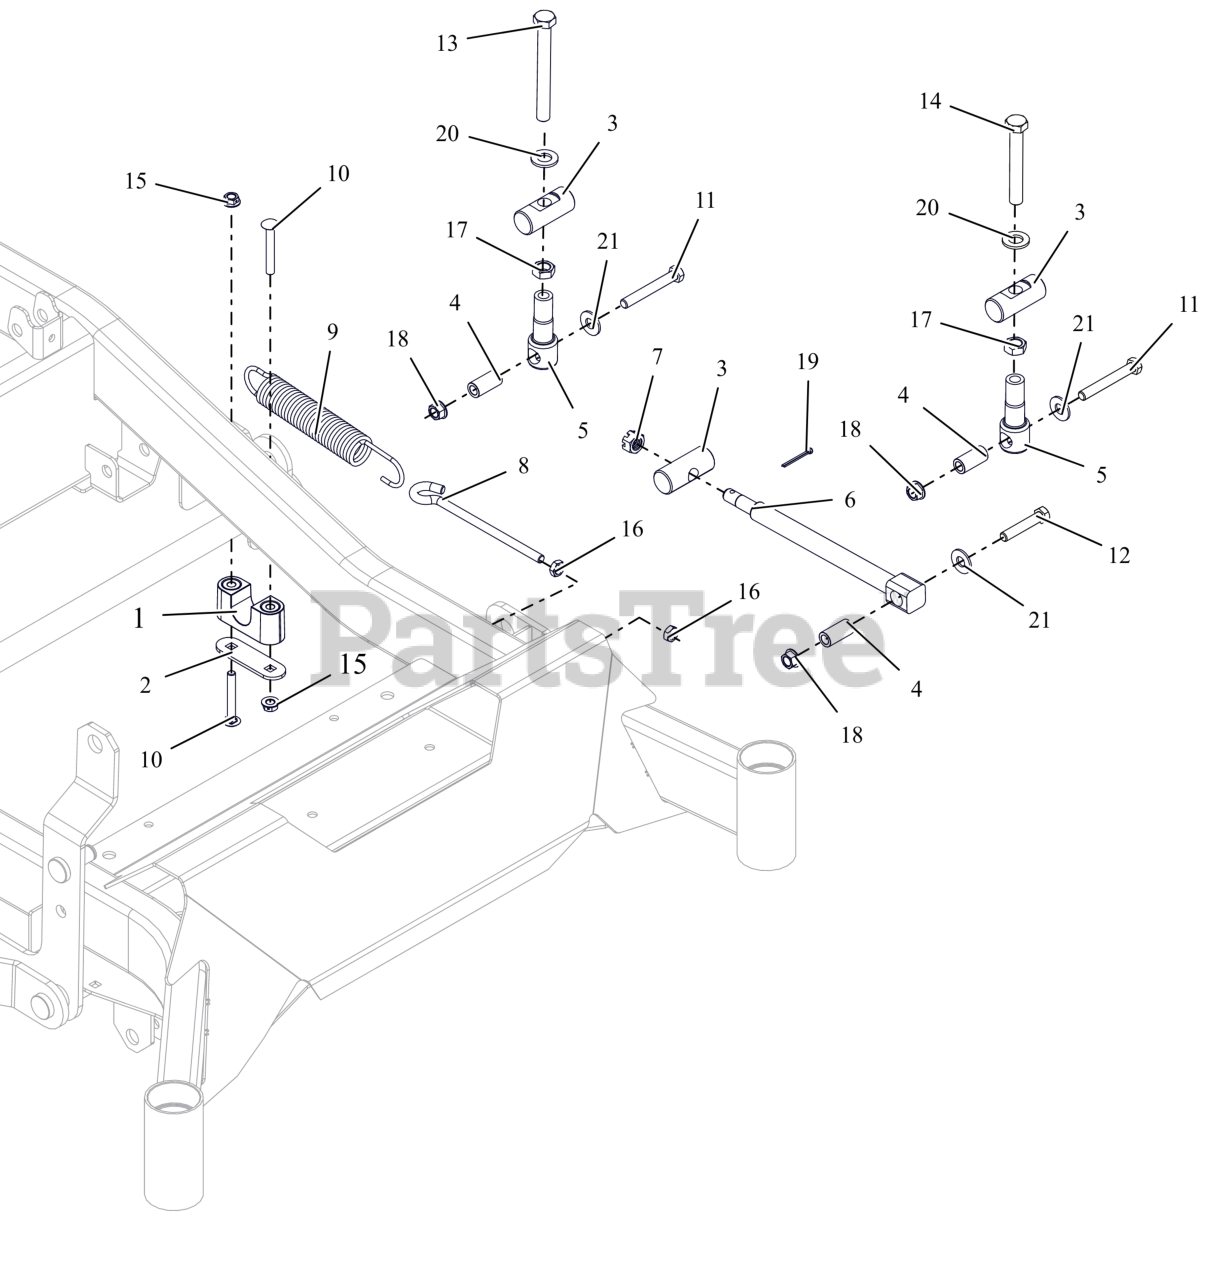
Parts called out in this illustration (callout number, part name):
1	ASM-BUSHING, DECK LIFT
2	PLATE, BEARING SUPPORT
3	PIN, DECK LIFT
4	SPACER, DECK LEVELING
5	LINK, DECK LIFT FORMED
6	DRAG,LINK-HD
7	NUT-SL .50-13
8	BOLT,.38-16 X 5.25-.62 DIA EYE
9	SG-TENS .162X1.25X8.25 WLD 25
10	BLT-RDHDSQSHNK .31-18X2.25 YWZ
11	BLT-HEX .38-16X2.75 GR8 YWZC
12	@BLT-HEX .38-16X2.00 GR5 YWZC
13	@BLT-HEX .5-13-4.5GR8 FULL THD
14	BLT-HEX .50-13X3.50 GR5 FTH
15	@NUT-LK-CTR-FLG .31-18 YZ GR F
16	NUT-HEX-JAM .375-16 YWZC
17	NUT-JAM .50-13 YWZC
18	@NUT-LK-TOP-FLG .38-16 YWZC
19	@PIN-CTR .12X1.25 EXTPRSQCT YZ
20	FLATWASHER 1/2 SAE HARD 15906
21	@WSHR-FL-STL.438X1.00X.083 YWZ
